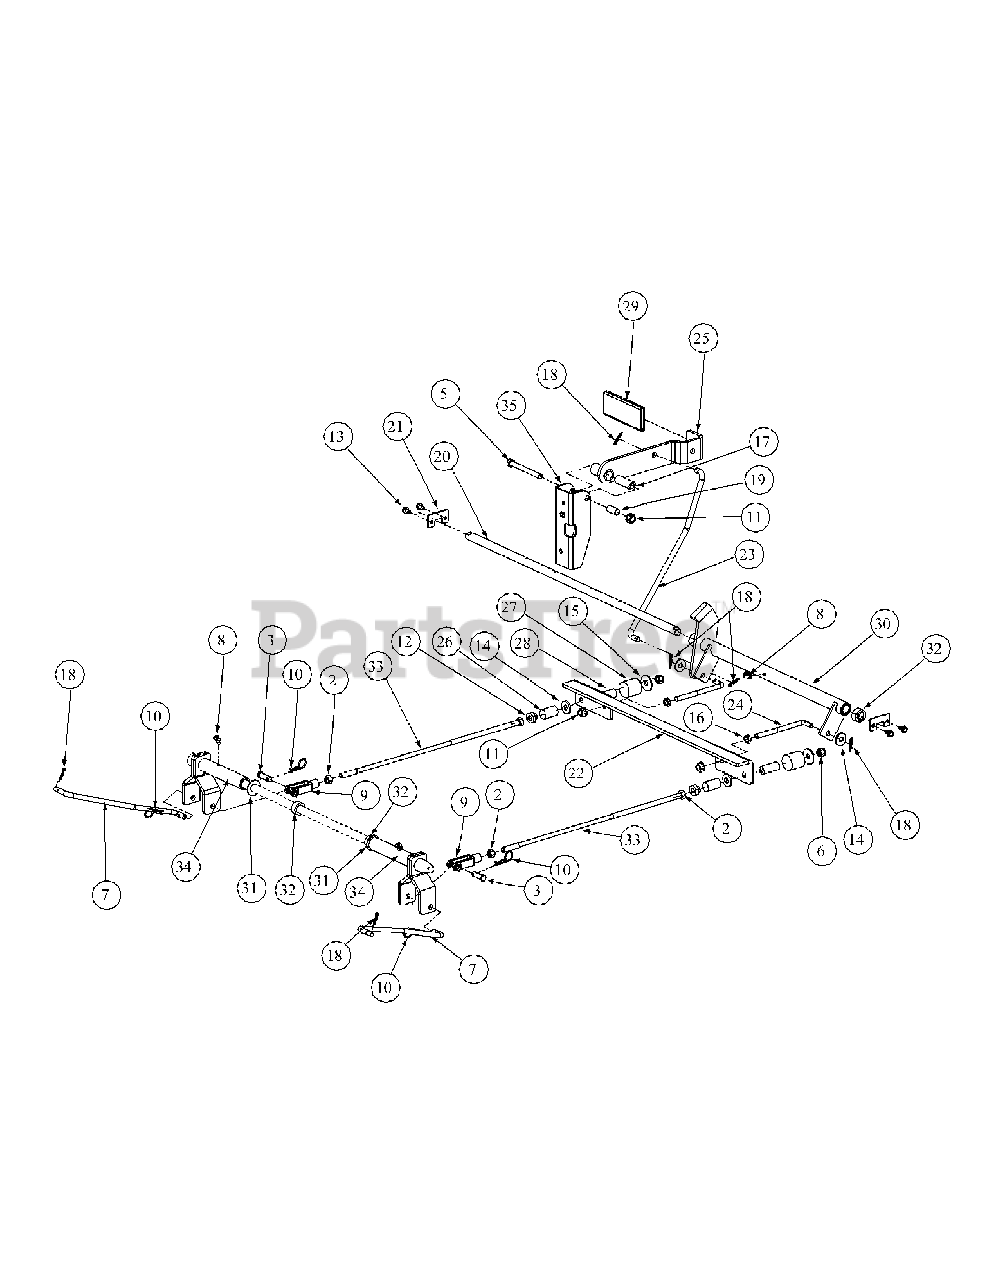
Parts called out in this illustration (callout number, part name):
2	Hex Nut, 3/8-16
3	Clevis Pin, 3/8 x 1-1/8
5	Hex Cap Screw, 3/8-16 x 3-1/2 OR
5	Hex Cap Screw, 3/8-16 x 3-1/4
6	Nylock Nut, 3/8-16
7	Rear Brake Linkage Rod
8	Grease Fitting, 1/4 -28, 90 degree
9	Yoke, 3/8-16
10	Hair Pin, 3/8" - 1/2"
11	Flange Lock Hex Nut, 3/8-16
12	Shoulder Nut
13	Screw, 1/4-20 x 1-1/2
14	Flat Washer, .406 ID x 1.0 OD x .105
15	Flat Washer, .411 x 1.25 x .100
16	Jam Nut, 3/8-16
17	Spacer, .375 x .50 x 1.75
18	Cotter Pin, .072 x 1.12 Lg
19	Spacer, .375 x .50 x 1.02 Lg
20	Bellecrank Mounting Shaft
21	Parking Brake Shaft Holder
22	Brake Bracket
23	Brake Rod
24	Connector Rod, 3/8 OD x 5.75
25	Brake Handle
26	Neutral Brake Spring
27	Force Brake Spring
28	Center Brake Hose
29	Parking Brake Grip
30	Brake Bearing Hub
31	Flat Washer, 5/8
32	Shaft Collar, .625 ID x 1" OD x .438
33	Connector Rod, 3/8 OD x 17.88 Lg
34	Rear Brake Arm Assembly
35	Parking Brake Mounting Bracket
